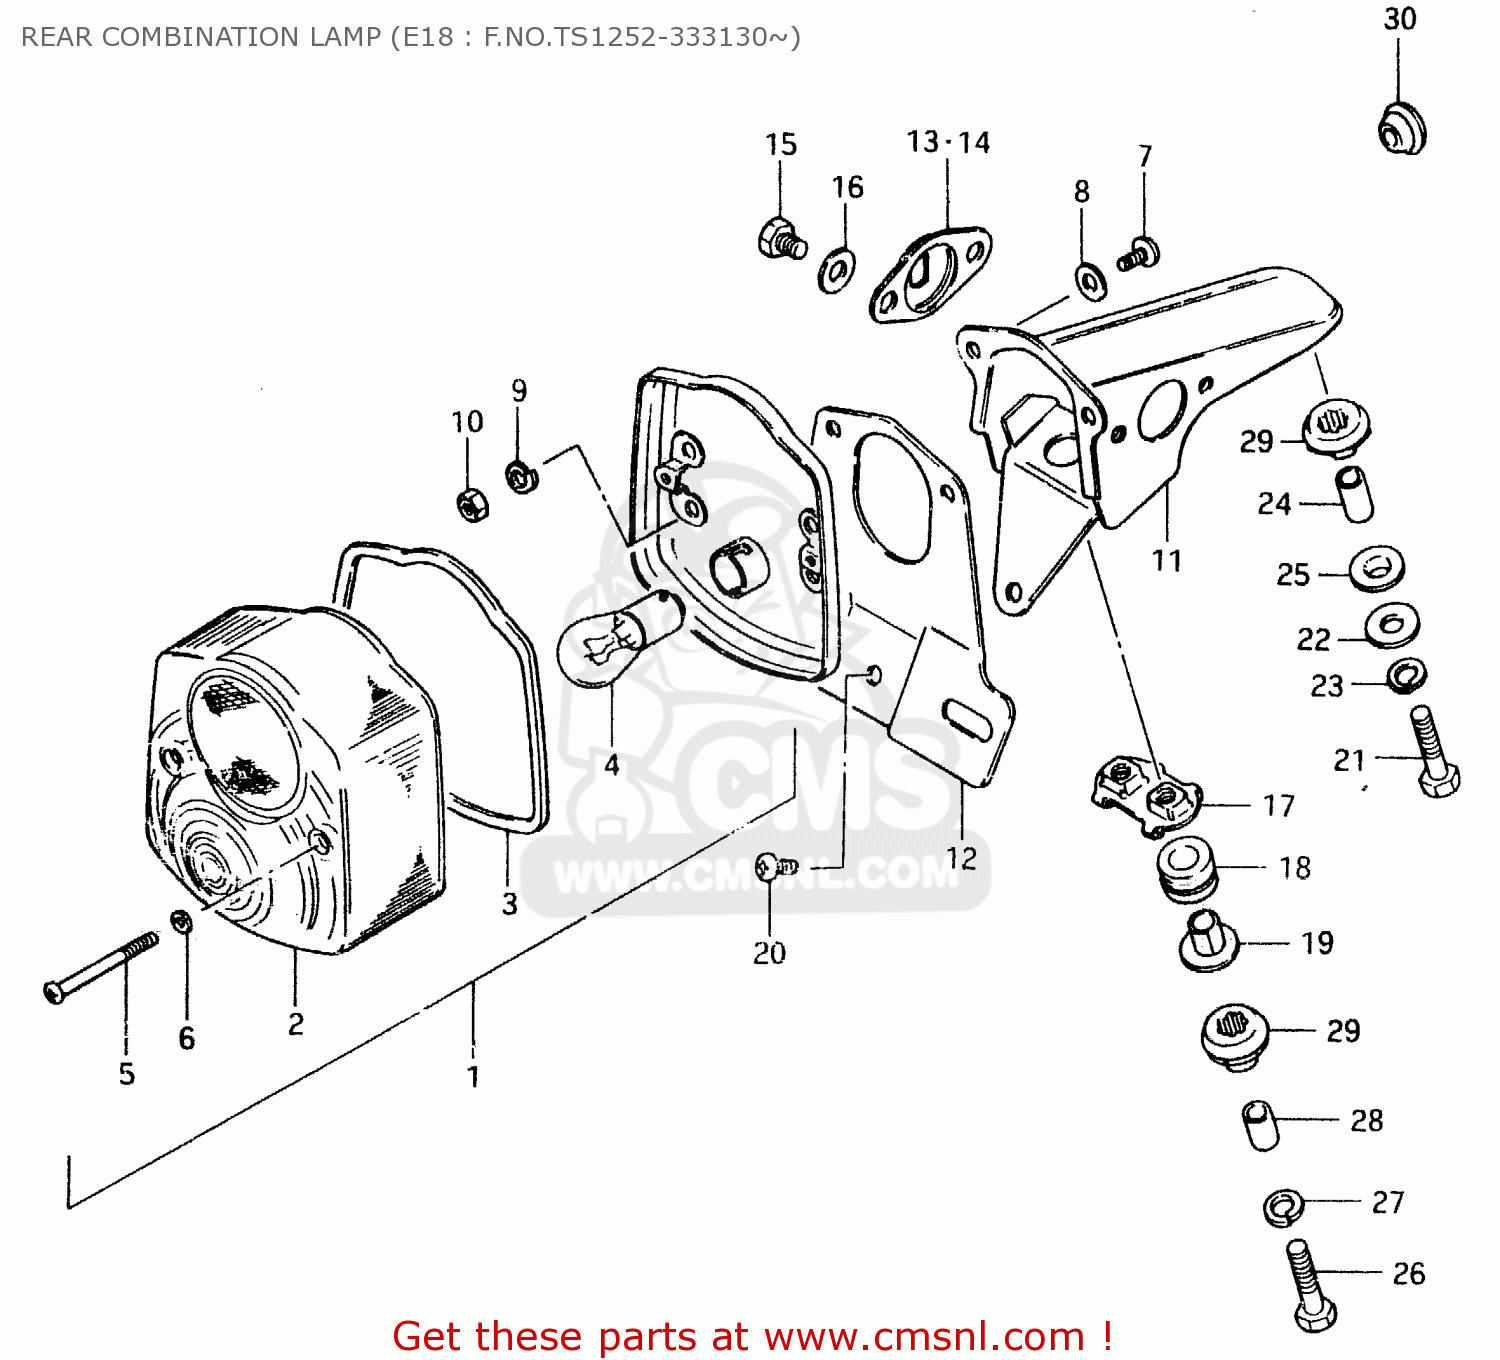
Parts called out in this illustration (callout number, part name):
1	LAMP UNIT, TAIL
2	LENS,RR COMBI
3	GASKET (NAS)
4	BULB (6V,21/5W)
5	SCREW
6	GASKET (NAS)
7	SCREW
8	WASHER
9	LOCK WASHER
10	NUT
11	BRACKET ASSY
12	PLATE, LICENSE
13	PLATE, RH
14	PLATE, LH
15	BOLT
16	WASHER
17	PLATE
18	CUSHION
19	SPACER
20	SCREW
21	BOLT
22	WASHER (6.5X20X1.2)
23	LOCK WASHER
24	SPACER
25	CUSHION
26	BOLT 6X40
27	LOCK WASHER
28	SPACER (6.8X10X11.5)
29	CUSHION
30	GROMMET
